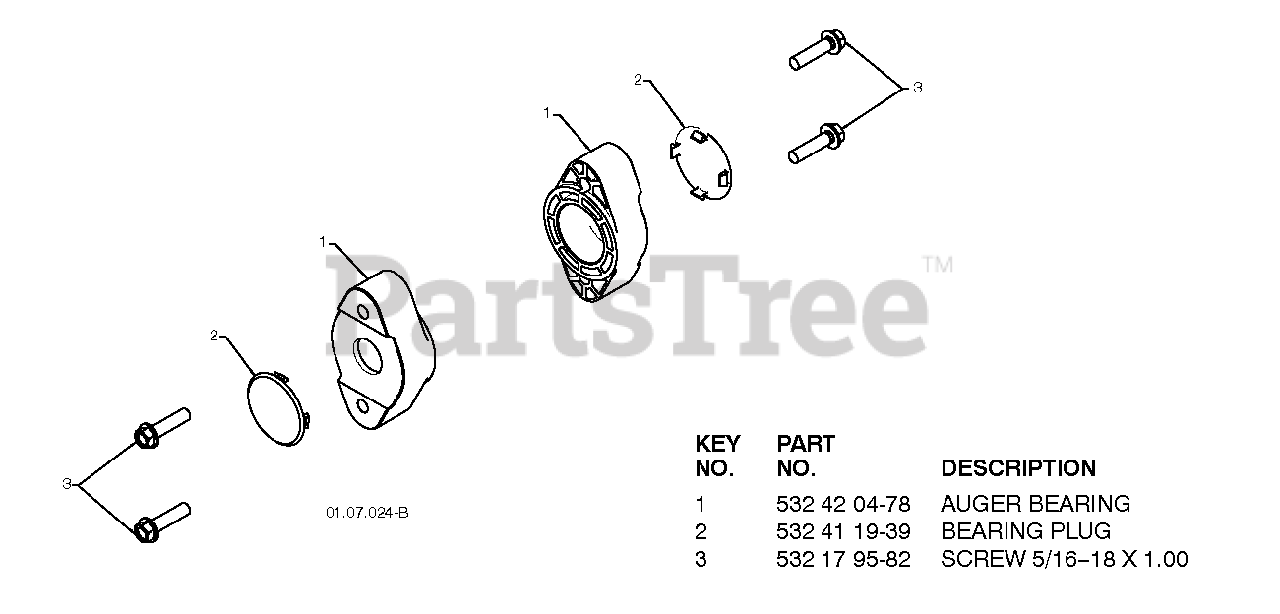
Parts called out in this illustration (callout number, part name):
1	BEARING.AUGER.SHAFT
2	PLUG.BEARING.HOLE.HSG
3	SCREW, HEX HD 5/16X1
